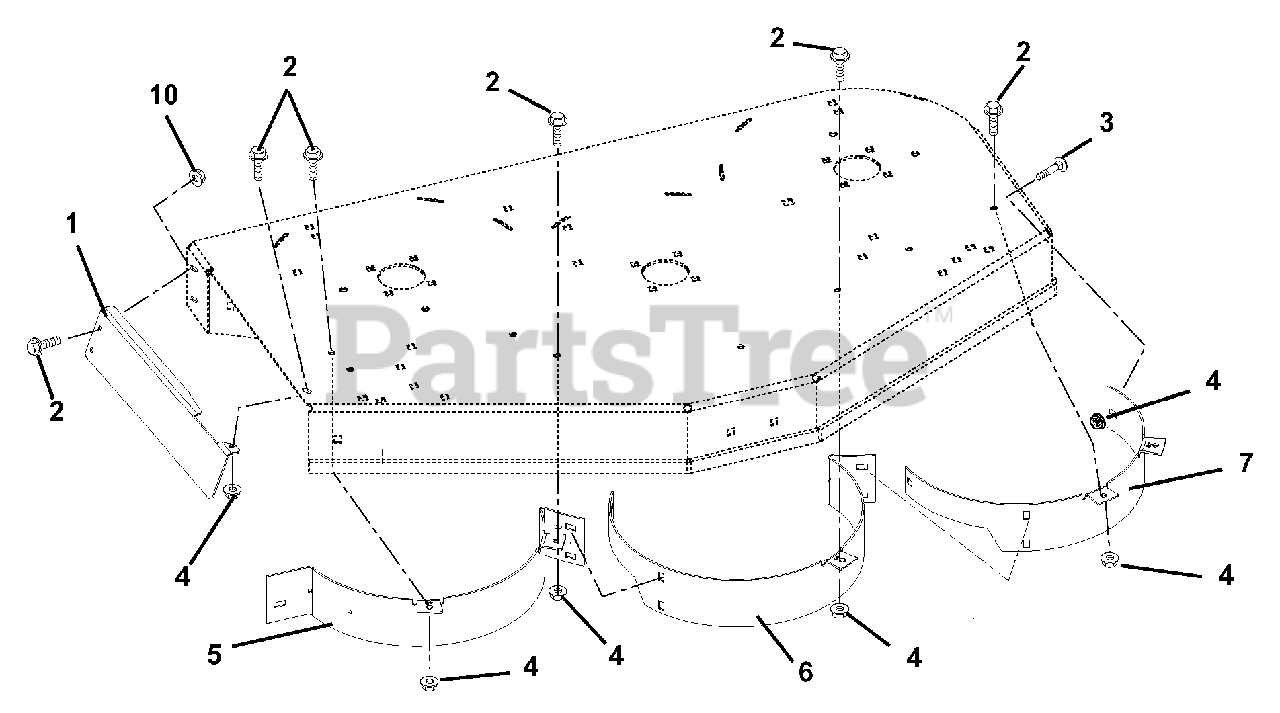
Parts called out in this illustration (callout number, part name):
1	BLOCK-OFF PLATE
2	BLT-SERHFWH .312-18X.75 YWZC
3	@BLT-RHDSSQNK .31-18X.75 G5YZ
4	@NUT-LK-NYL-FLG .31-18 YWZC
5	BAFFLE-MULCH-RIGHT FRONT-40"
5	BAFFLE-MULCH-RIGHT FRONT-44"
6	BAFFLE-MULCH-CENTER FRONT-40"
6	BAFFLE-MULCH-CENTER FRONT-44"
7	BAFFLE-MULCH-LEFT FRONT-40"
7	BAFFLE-MULCH-LEFT FRONT-44"
